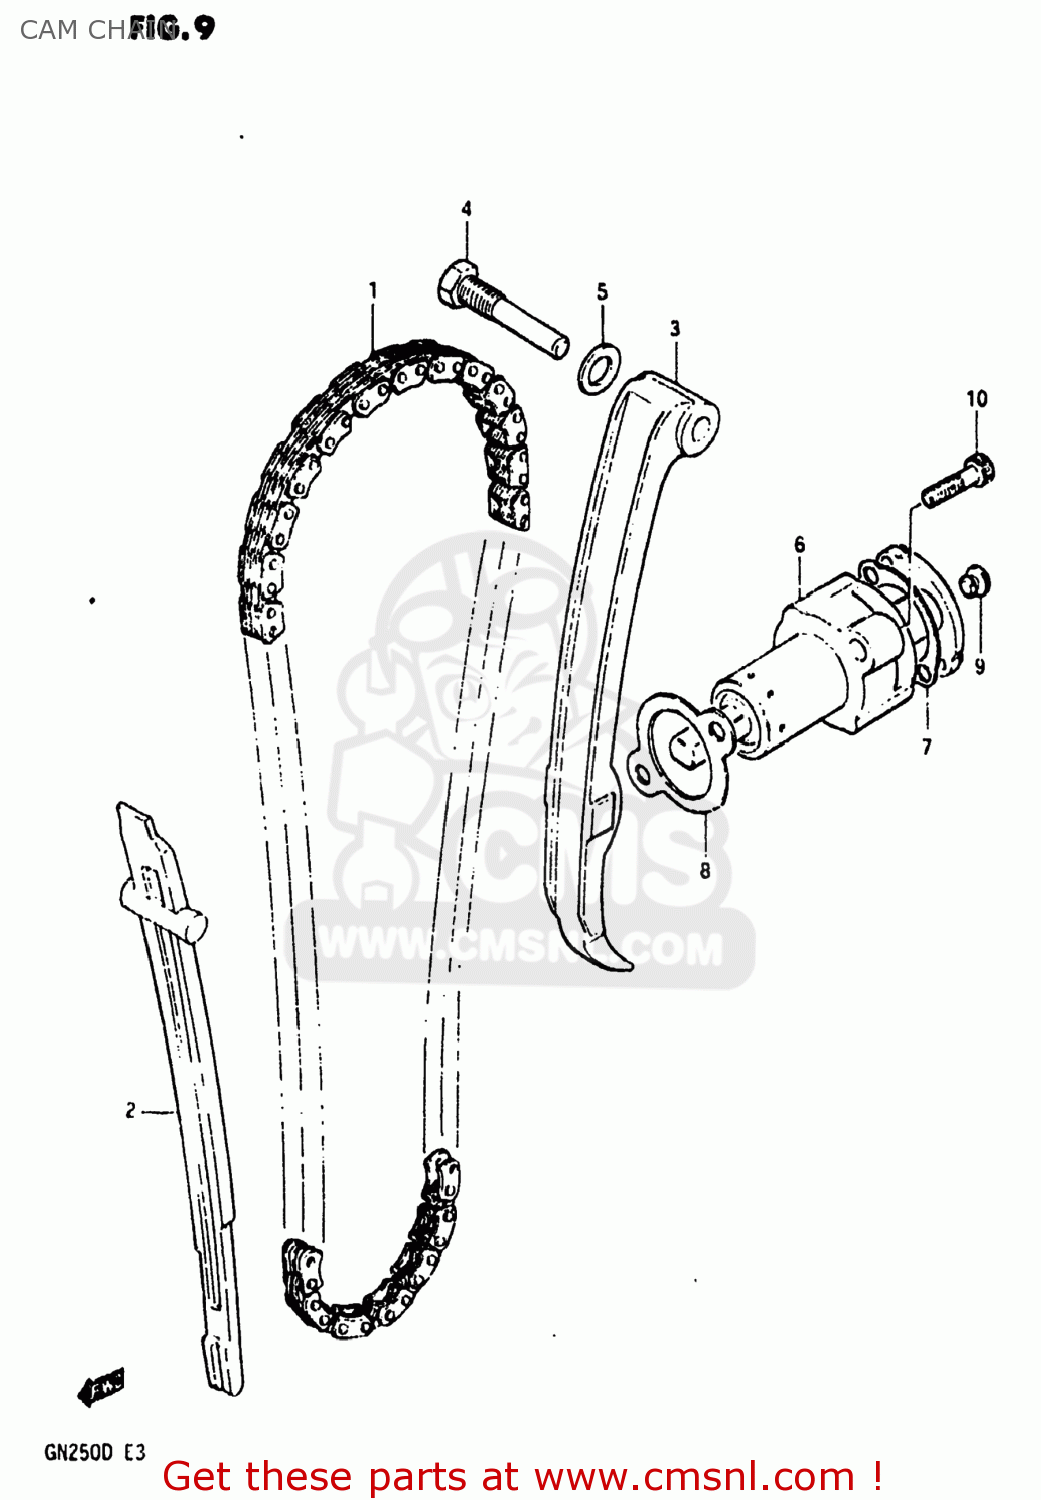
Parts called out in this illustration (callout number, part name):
1	CHAIN,CAMSHAFT DRIVE
2	GUIDE,CAM CHAIN
3	TENSIONER,CAM CHAIN
4	BOLT,CAM CHAIN TENSIONER
5	GASKET 8.2X14X1 (NAS)
6	ADJUSTER ASSEMBLY,TENSIONER
7	GASKET,ADJUSTER CAP (MCA)
8	GASKET,TENSIONER ADJUSTER (MCA)
9	PLUG,ADJUSTER
10	BOLT
